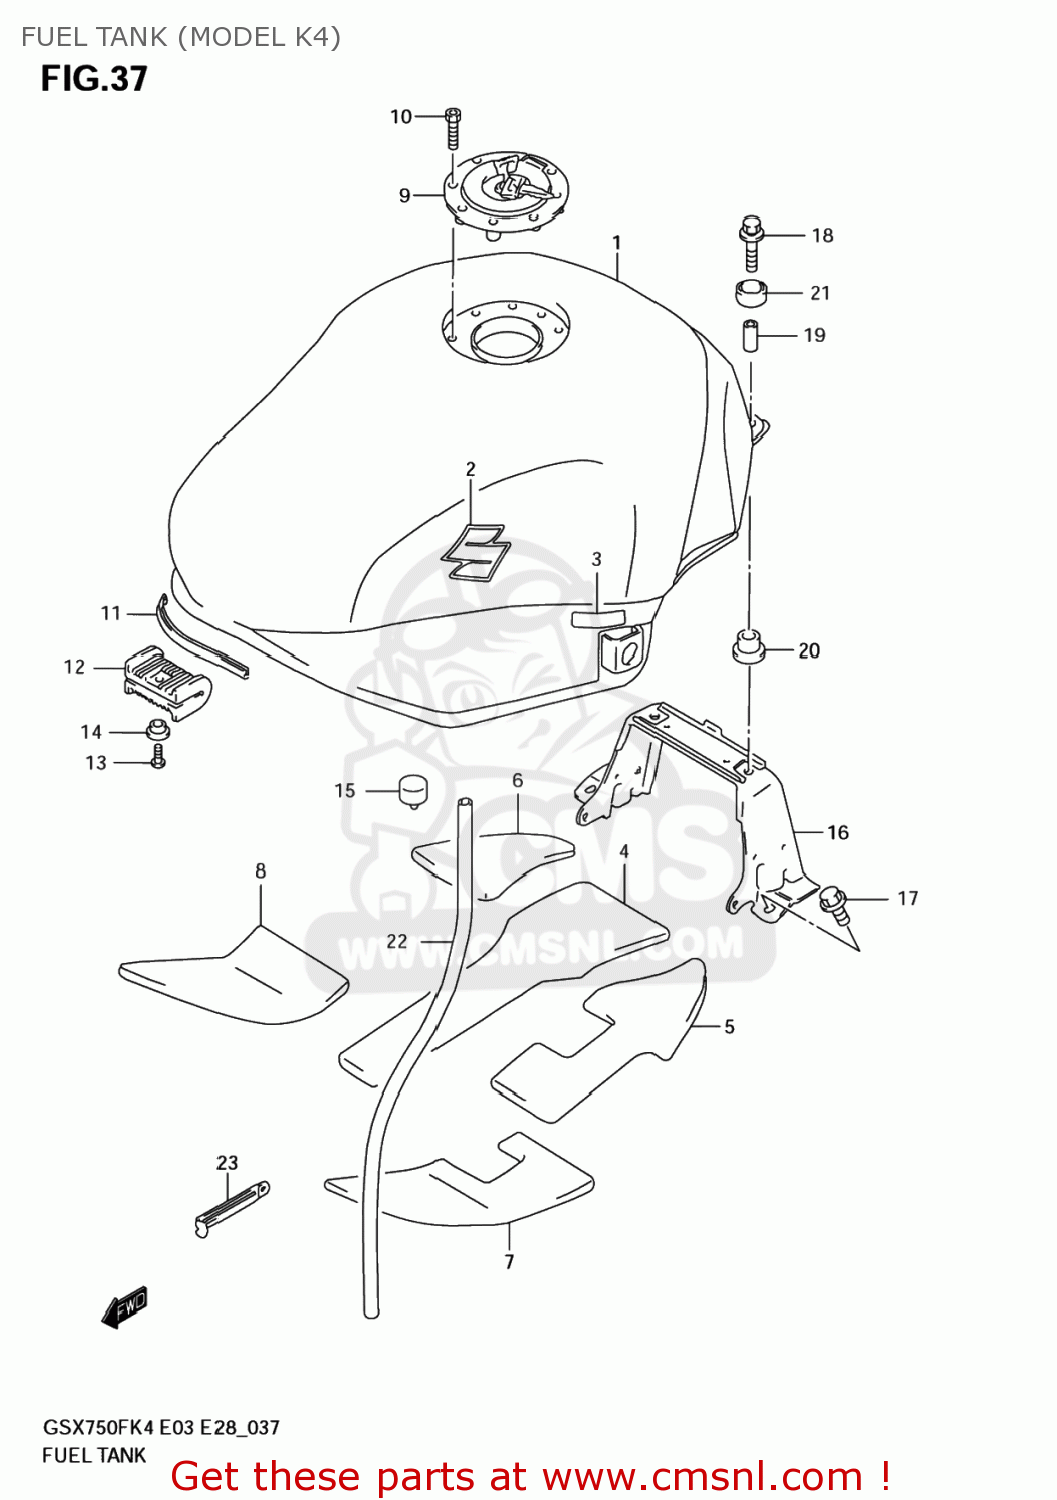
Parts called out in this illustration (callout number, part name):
1	TANK ASSY,FUEL(GRAY)
2	EMBLEM,FUEL TA
3	PROTECTOR(12X40)
4	SHIELD,FUEL TANK HEAT NO.1
5	SHIELD,FUEL TANK HEAT NO.2
6	SHIELD,FUEL TANK HEAT NO.3
7	SHIELD,FUEL TANK HEAT NO.4
8	SHIELD,FUEL TANK HEAT NO.5
9	CAP SET,FUEL TANK
10	BOLT(5X20)
11	MOLDING,FUEL TANK
12	CUSHION,FUEL TANK FR
13	SCREW 5X12
14	WASHER
15	CUSHION
16	BRACKET,FUEL TANK RR
17	BOLT
18	BOLT(6X30)
19	SPACER(6.5X9X18)
20	CUSHION
21	CUSHION
22	HOSE,FUEL TANK WATER DRAIN
23	CLAMP(L:120 T:1.0)
